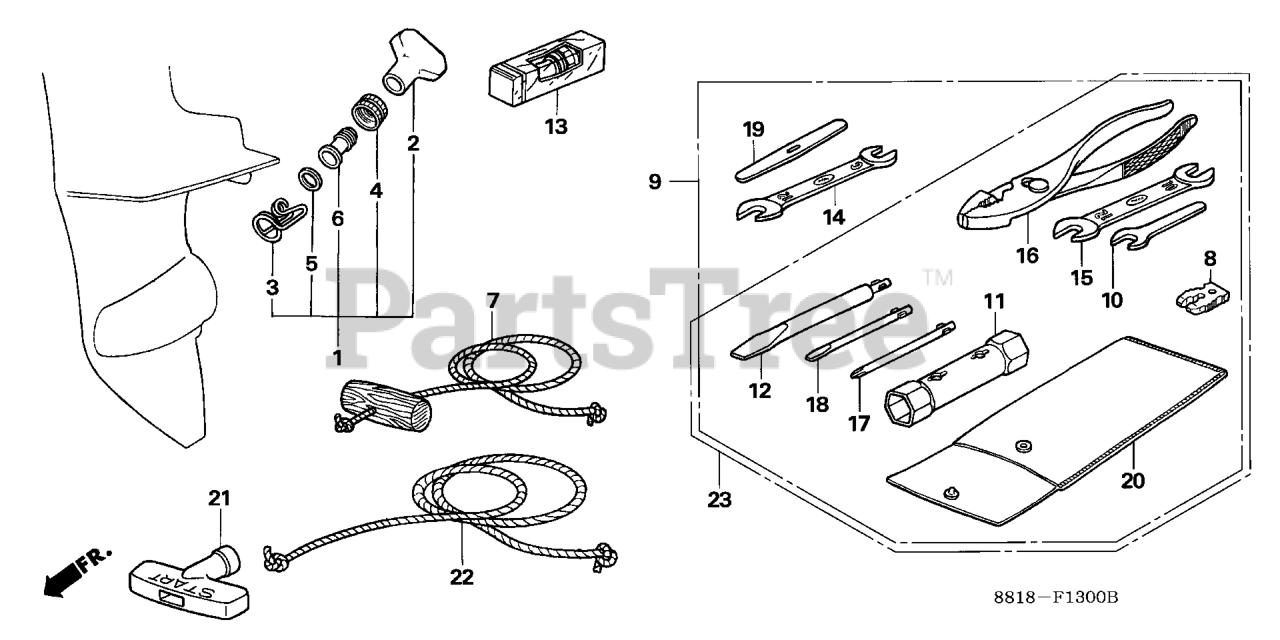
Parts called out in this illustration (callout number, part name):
2	MOUTH, WATER Use from Frame SN 1000929.
3	CLIP, WATER MOUTH Use from Frame SN 1000929.
4	NUT, WATER MOUTH Use from Frame SN 1000929.
5	SEAT, WATER MOUTH Use from Frame SN 1000929.
6	JOINT, HOSE Use from Frame SN 1000929.
8	CLIP, EMERGENCY LOCK
10	WRENCH (8MM) (OPEN END) (NOT AVAILABLE)
11	WRENCH, BOX (P18X19)
12	SCREWDRIVER, CHECK BOLT
13	SPARK PLUG (DR5HS) (NGK)
15	WRENCH (10X12) (OPEN END)
16	PLIERS (135) (RIKEN)
17	SCREWDRIVER 1, PHILLIPS (NO.2)
18	SCREWDRIVER 3, STRAIGHT SLOT (NO. 2)
20	BAG, TOOL (160MM)
21	GRIP, STARTER
22	ROPE, RECOIL STARTER (1300MM)
